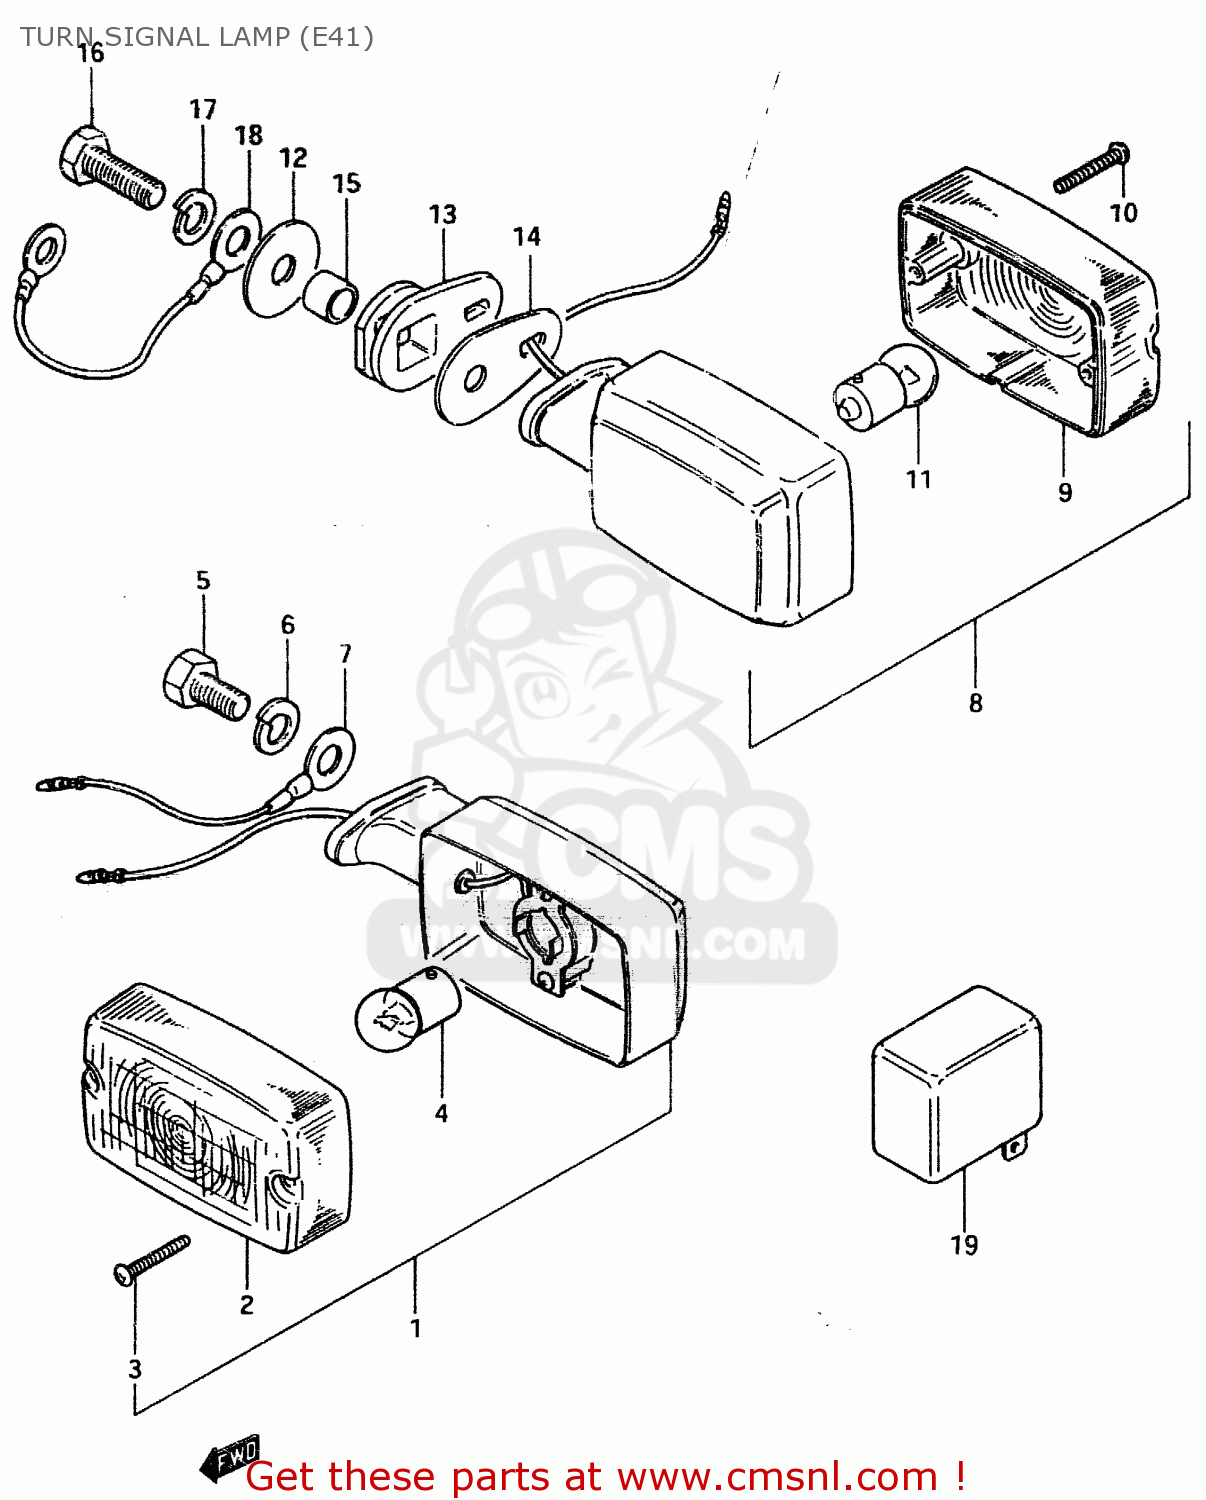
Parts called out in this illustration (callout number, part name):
1	LAMP, REAR TURN SIGNAL
2	LENS
3	SCREW
4	BULB(6V/10W,STANLEY,A4117)
5	BOLT
6	LOCK WASHER
7	WIRE
8	LAMP, REAR TURN SIGNAL
9	LENS
10	SCREW
11	BULB(6V/10W,STANLEY,A4117)
12	WASHER
13	CUSHION
14	PLATE
15	SPACER (8.8X12X11)
16	BOLT (8X30)
17	LOCK WASHER
18	LEAD WIRE
19	RELAY, TURN SIGNAL
